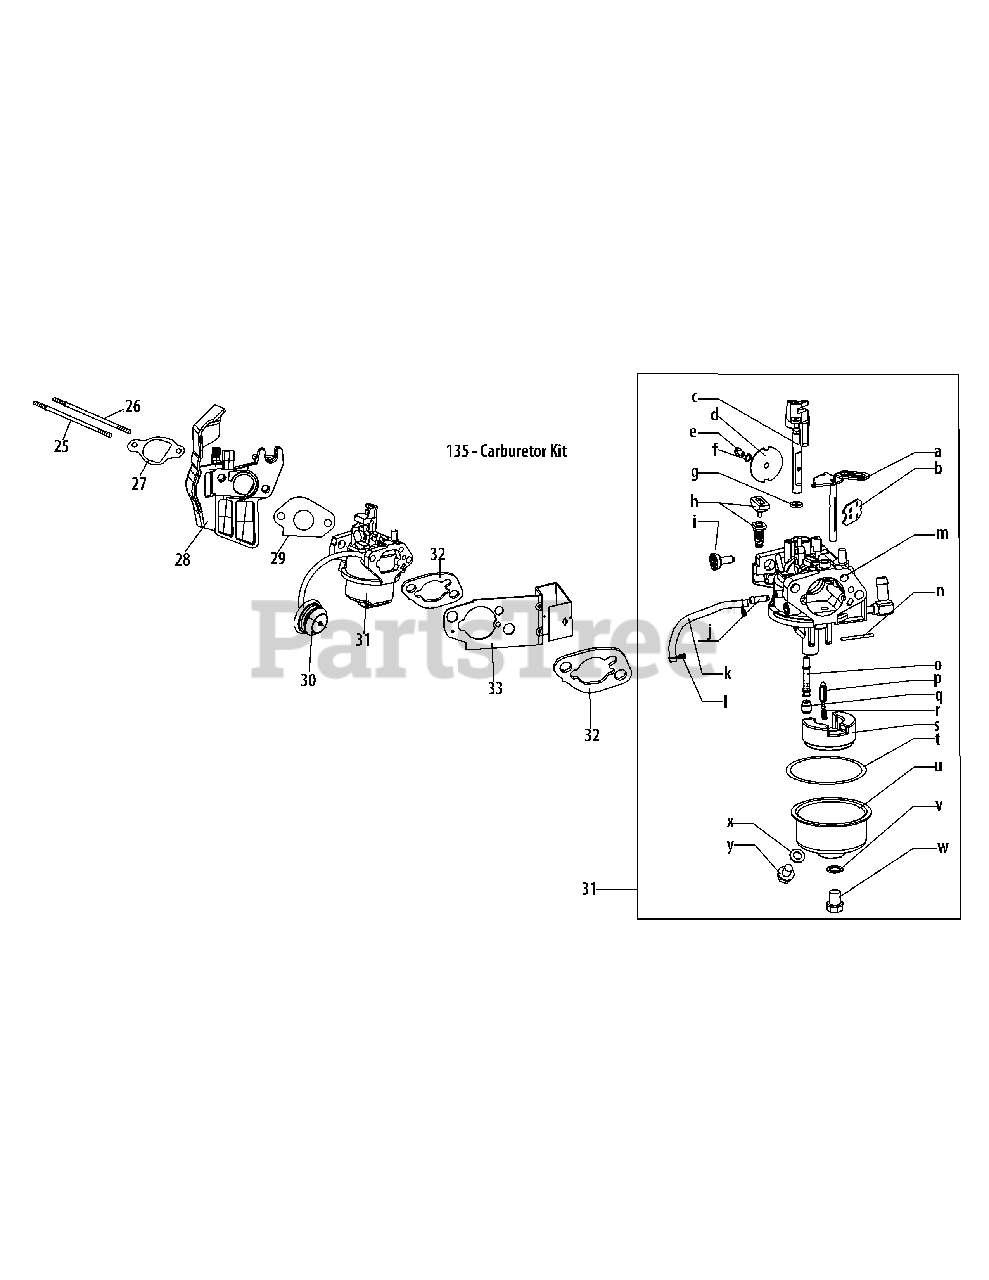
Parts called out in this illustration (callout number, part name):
25	Stud M6×117
26	Stud M6×105
27	Carburetor Insulator Gasket
28	Carburetor Insulator
29	Carburetor Gasket
30	Primer Assembly
30	Primer Bulb
31	Carburetor Assembly
32	Carburetor Gasket Plate
33	Choke Control
135	Carburetor Kit
